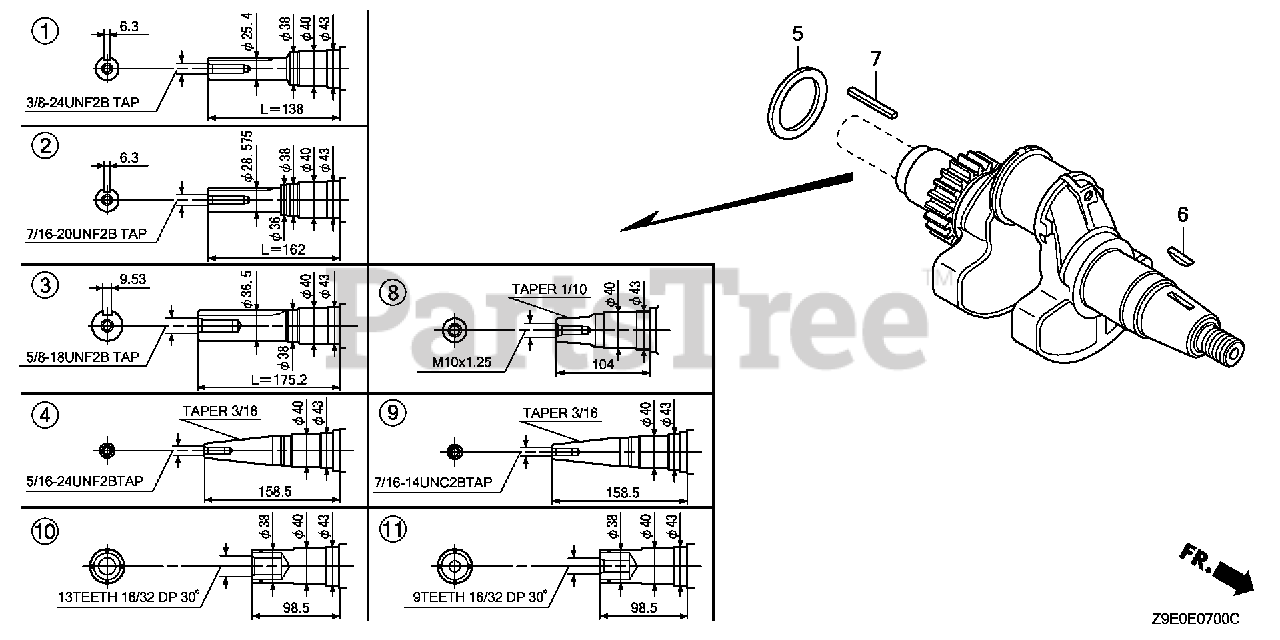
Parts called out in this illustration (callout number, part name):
5	WASHER, CRANKSHAFT THRUST
6	KEY, SPECIAL WOODRUFF (25X18)
8	CRANKSHAFT
